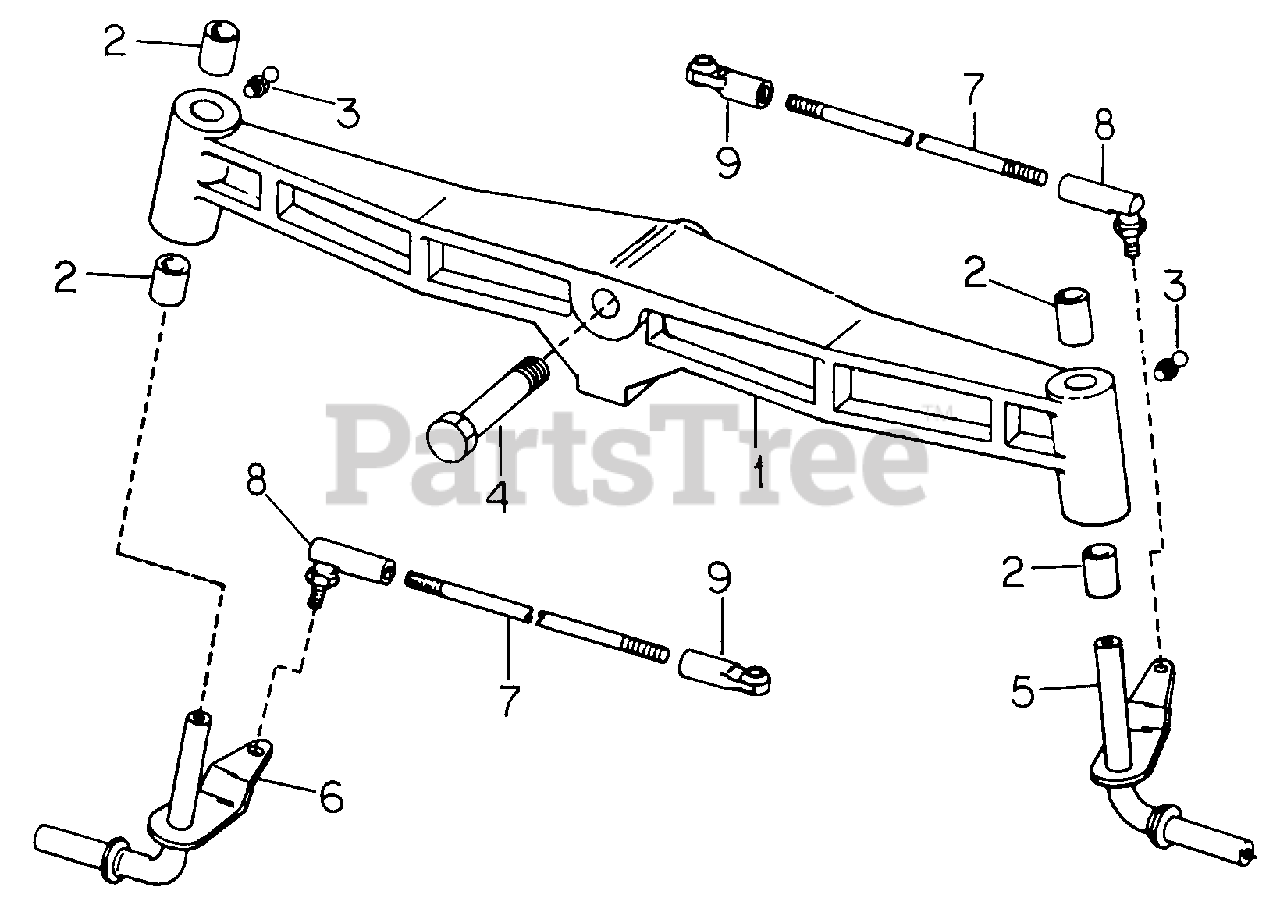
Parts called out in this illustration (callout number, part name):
1	Axle Assy w/Bushing Front
3	Fitting, 3/16 Drive Type Str Lub
4	Bolt, Axle Pivot
5	Knuckle Assy, Steering, LH
6	Knuckle Assy, Steering, RH
8	Joint, Ball
9	Joint, Ball
IH-Q3480	Washer, 1.031 X 1.500 X .105 Pln
